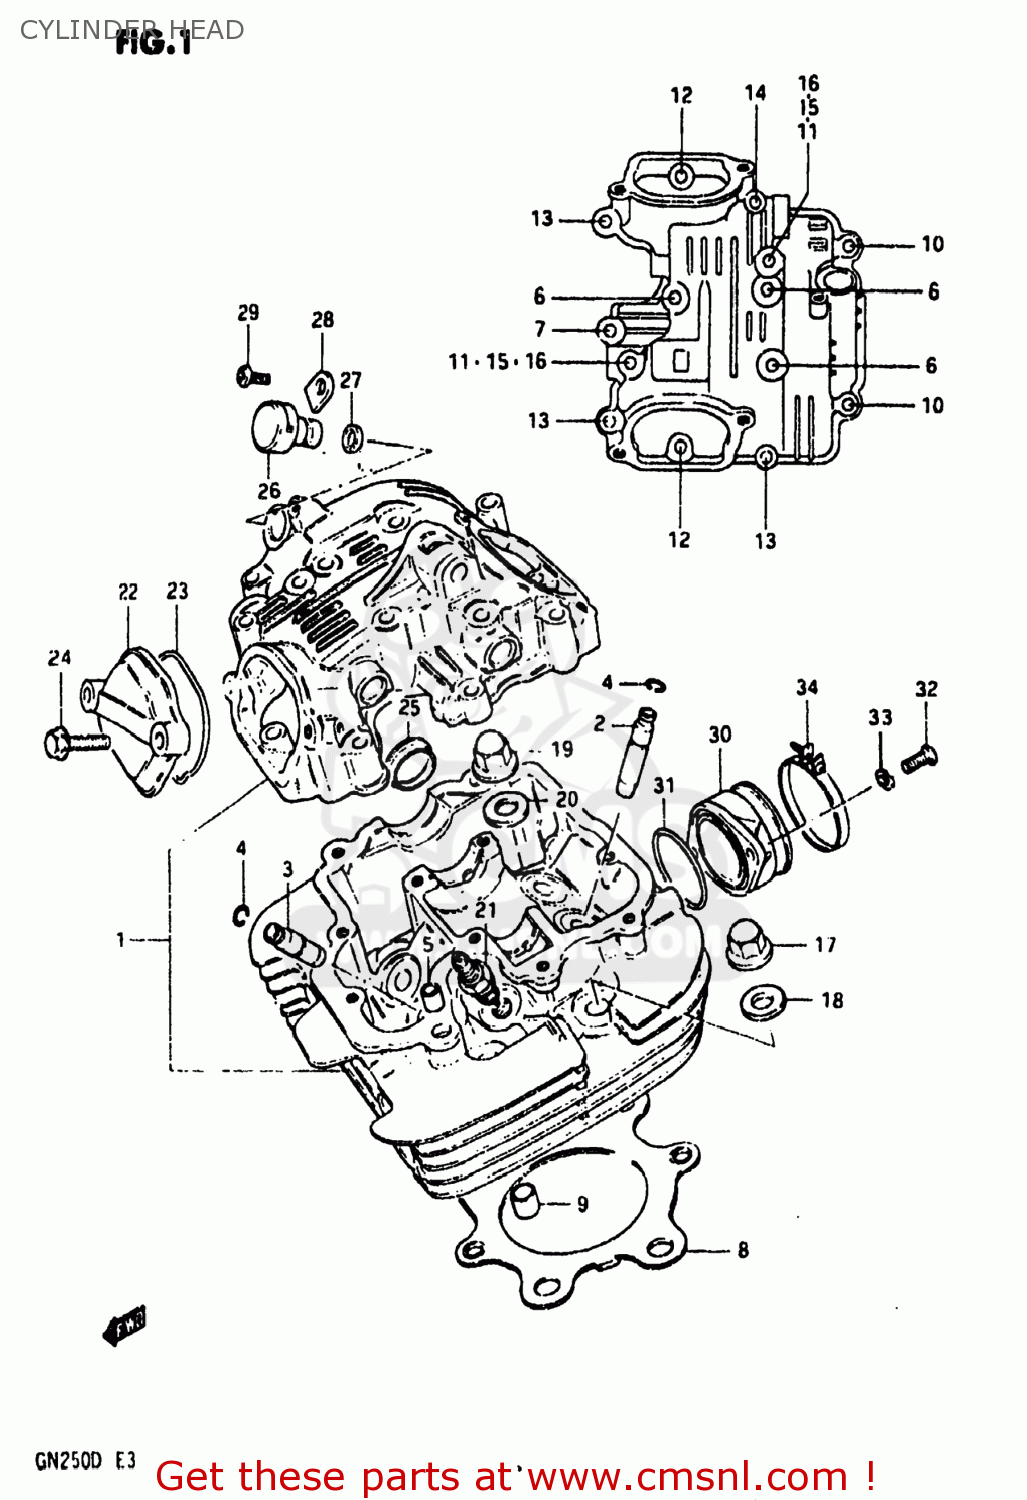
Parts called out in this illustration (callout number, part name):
1	HEAD ASSEMBLY,CYLINDER
2	GUIDE,INTAKE VALVE
3	GUIDE,VALVE
4	RING,SNAP
5	PIN(6.2X8X11)
6	BOLT (6X60)
7	BOLT
8	GASKET,CYLINDER HEAD (NAS)
9	PIN
10	BOLT(6X115)
11	STUD 6X30
12	BOLT
13	BOLT,UNDER
14	BOLT (6X60)
15	NUT
16	GASKET (NAS)
17	NUT
18	WASHER(10.5X22X2.3)
19	NUT
20	GASKET(10.5X22X2) (NAS)
21	SPARK PLUG D8EA
22	CAP,INSPECTION
23	O RING(D:2.4,ID:23)
24	BOLT (6X75)
25	PLUG(OD:30)
26	PLUG,TACH GEAR SLEEVE HOLE
27	SEAL,TACHOMETER DRIVEN
28	PLATE,TACH DRIVE GEAR SLEEVE
29	SCREW(5X12)
30	PIPE,INTAKE
31	O-RING (D:2.4 ID:39.7)
32	SCREW
33	LOCK WASHER
34	CLAMP
